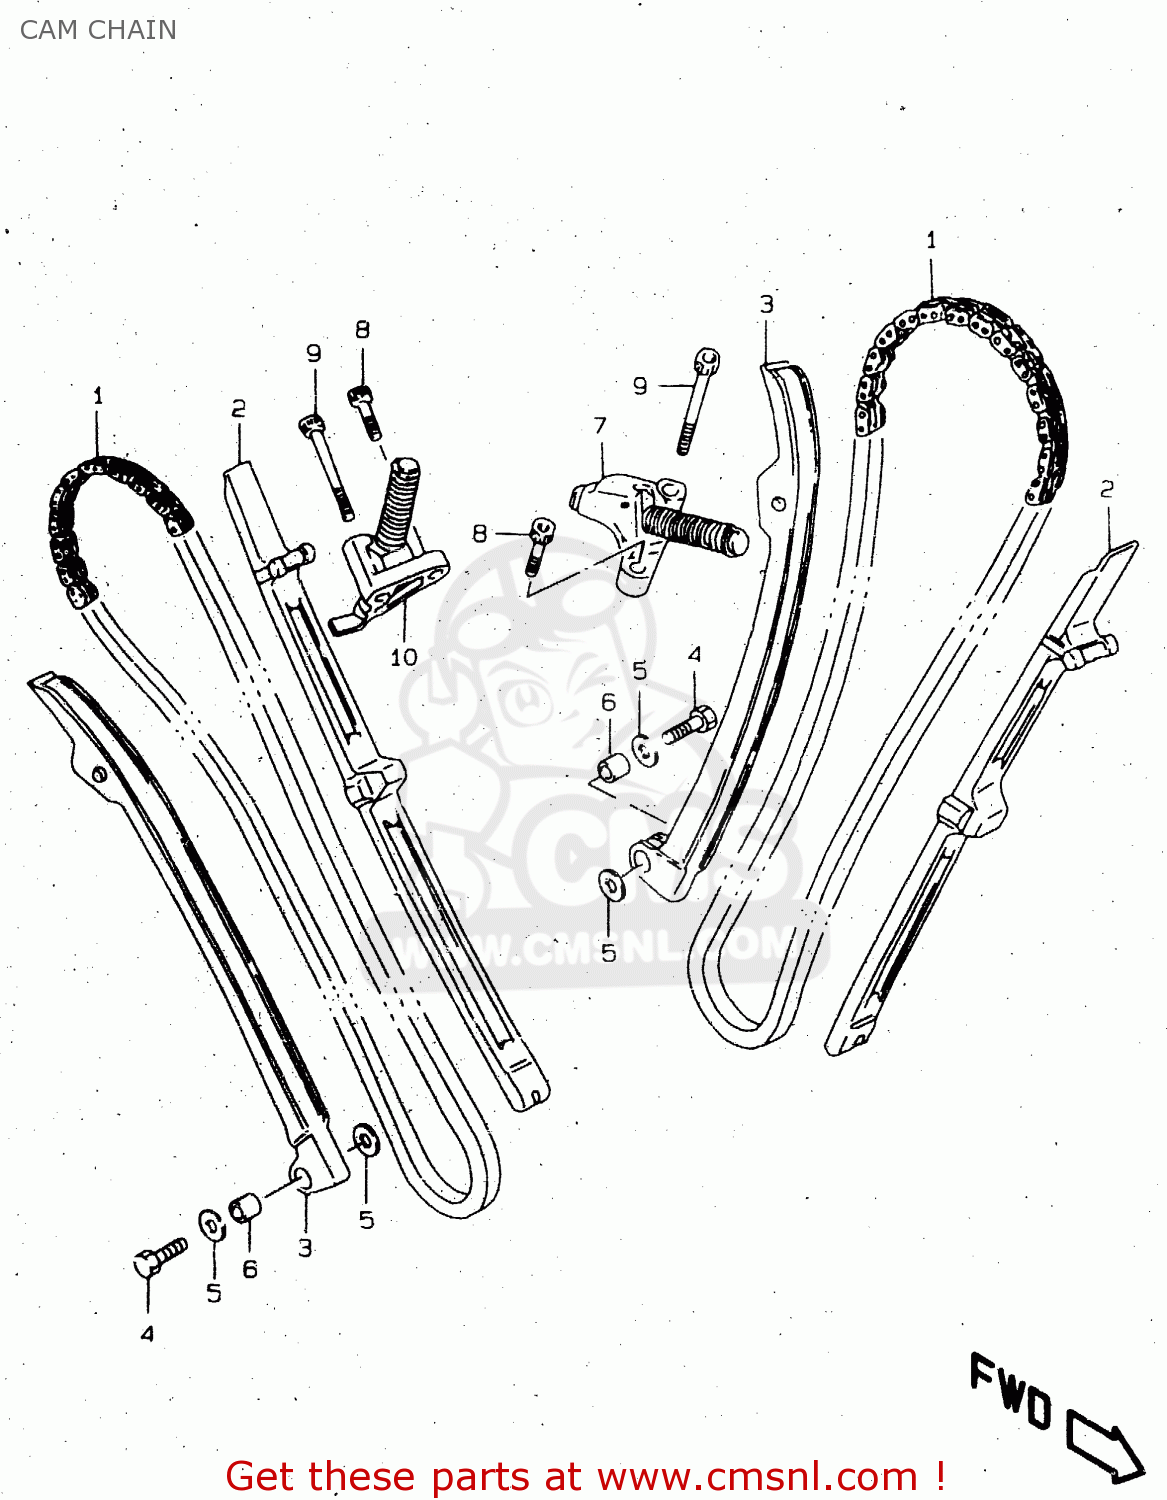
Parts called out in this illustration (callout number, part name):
1	CHAIN,CAMSHAFT DRIVE
2	GUIDE,CAM CHAIN
3	TENSIONER,CAM CHAIN
4	BOLT(6X26)
5	WASHER
6	SPACER(6X11X9)
7	ADJUSTER ASSEMBLY,FRONT TENSIONER
8	BOLT,CRKCASE,R
9	BOLT
10	ADJUSTER ASSEMBLY,REAR TENSIONER
